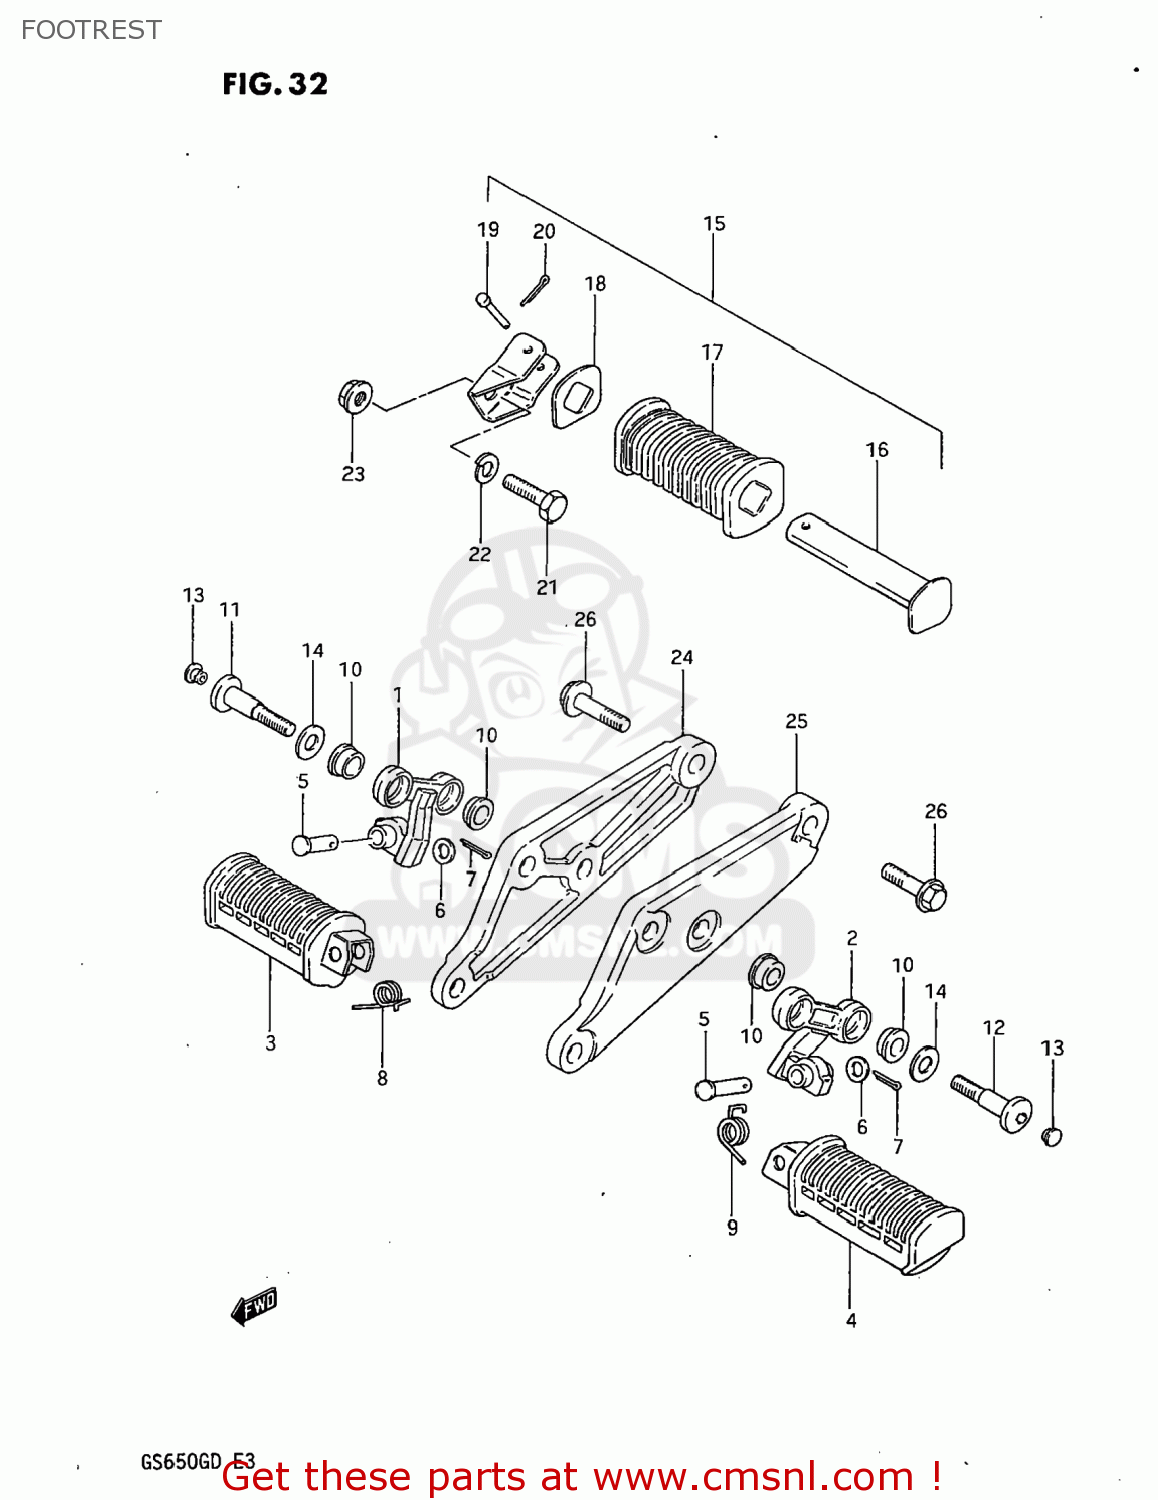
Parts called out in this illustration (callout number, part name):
1	BAR,FRONT FOOTREST,RIGHT
2	BAR,FRONT FOOTREST,LEFT
3	RUBBER,FOOTREST
4	FOOTREST
5	PIN
6	WASHER
7	PIN 20X20
8	SPRING
9	SPRING
10	BUSH
11	BOLT
12	BOLT
13	CAP
14	WASHER(10.5X28X2.3)
15	FOOTREST ASSY,PILLION,R
16	BAR,REAR FOOTREST,LEFT
17	RUBBER,PILLION FOOTREST
18	WASHER,FOOTREST RUBBER
19	PIN
20	PIN 20X20
21	BOLT,M10X1.25X
22	LOCK WASHER
23	NUT
24	BRACKET,MUFFLER,RIGHT
25	BRACKET,MUFFLER,LEFT
26	BOLT
